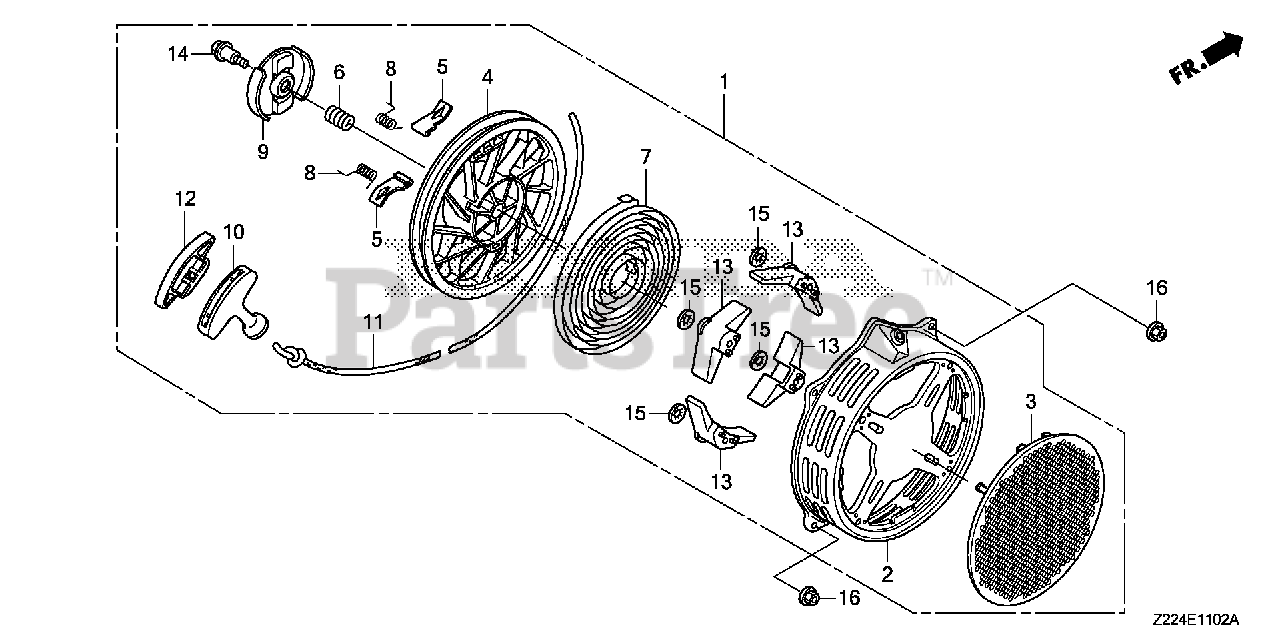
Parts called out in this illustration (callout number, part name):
1	STARTER ASSY., RECOIL *NH1* (COO)(FOR U.S.A.) (BLACK)
2	CASE, RECOIL STARTER *NH1* (BLACK)
3	COVER, RECOIL STARTER
4	PULLEY, RECOIL STARTER
5	RATCHET, STARTER
6	SPRING, FRICTION
7	SPRING, STARTER RETURN
8	SPRING, RATCHET
9	RETAINER, SPRING
10	GRIP, STARTER
10	GRIP, STARTER (COO)(FOR U.S.A.)
11	ROPE, RECOIL STARTER
12	GRIP, REINFORCEMENT
13	COVER, ROPE
14	SCREW, CENTER
16	NUT, FLANGE (6MM)
